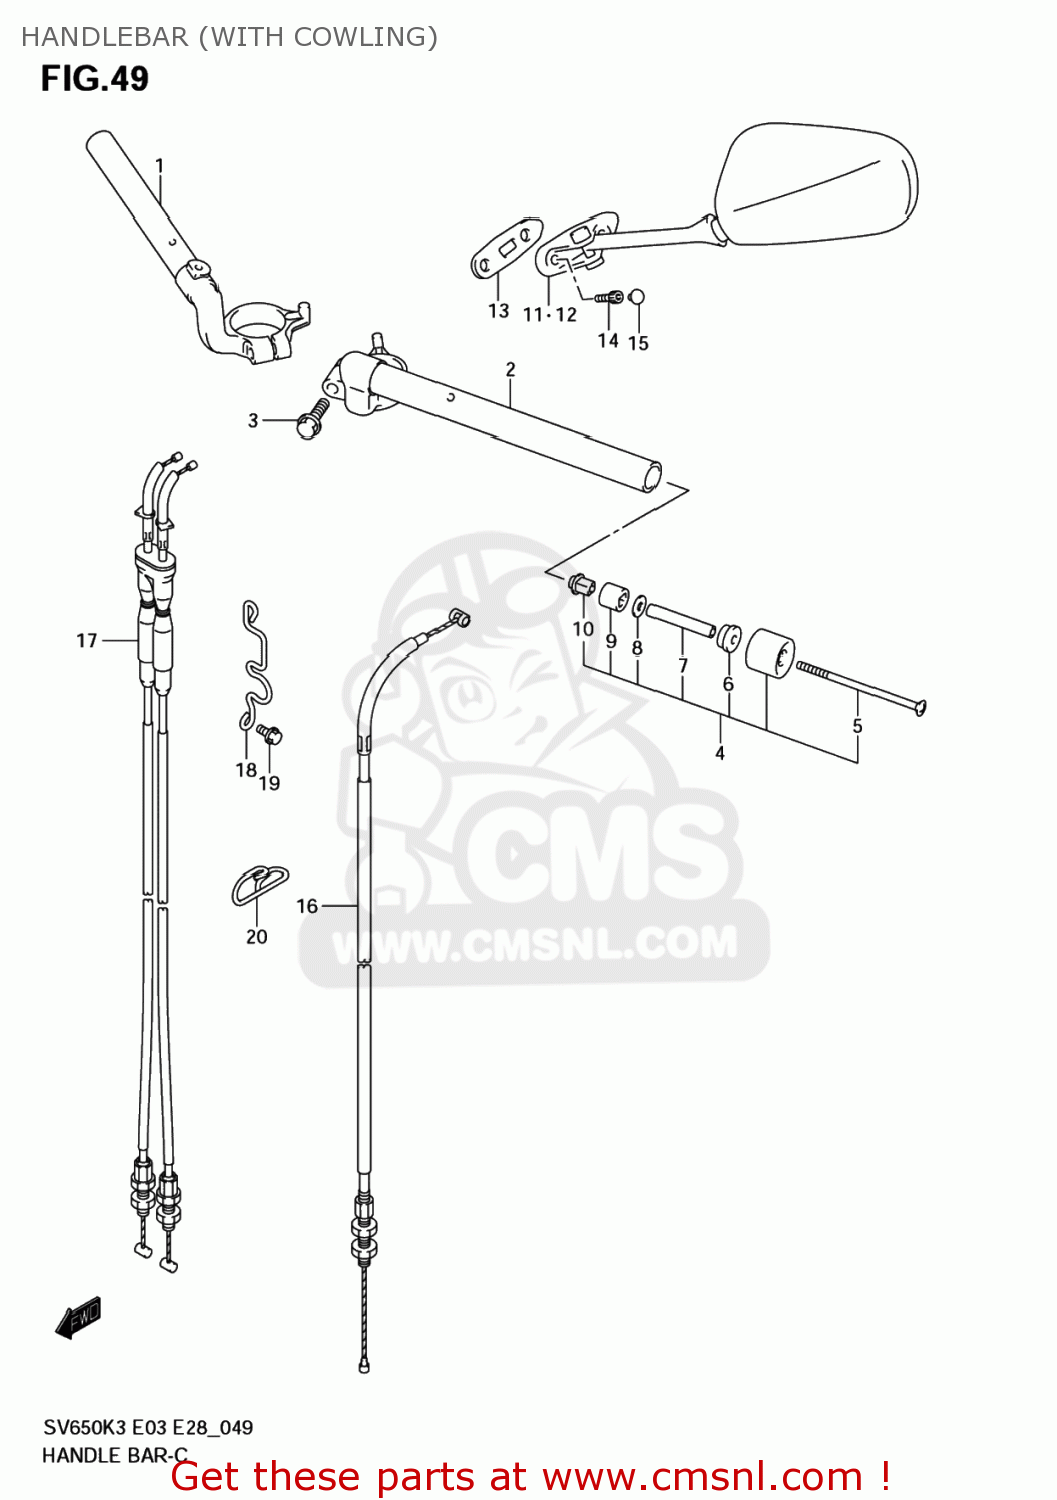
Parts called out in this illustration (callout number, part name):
1	HANDLEBAR,R
2	HANDLEBAR,L
3	BOLT,HANDLEBAR
4	BALANCER SET,H
5	SCREW,HANDLE B
6	EXPANDER,HANDLE BALANCER
7	SPACER,EXPANDER
8	WASHER(6.5X16X1.6)
9	EXPANDER,HANDLE BALANCER
10	NUT,HANDLE BAL
11	MIRROR ASSY,RE
12	MIRROR ASSY,RE
13	CUSHION,RR VIEW MIRRORR
14	BOLT,OIL FILLE
15	CAP(OD:10)
16	CABLE ASSY,CLUTCH
17	CABLE ASSY,THROTTLE
18	GUIDE,CABLE L
19	BOLT
20	GUIDE,THROTTLE CABLE
